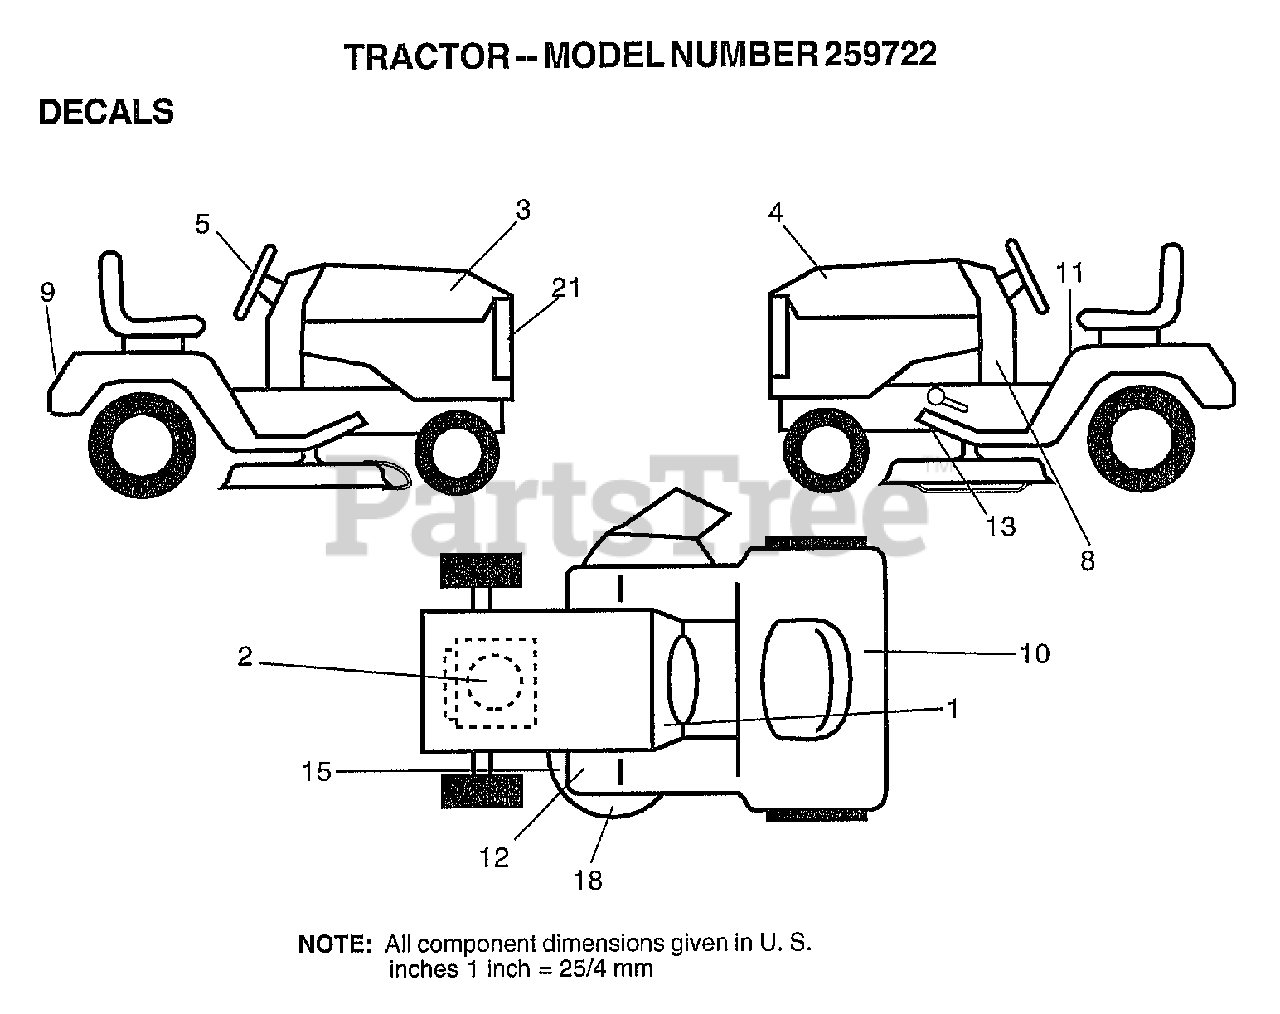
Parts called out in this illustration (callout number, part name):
1	"DECAL DASH,OPER."
2	DECAL HP ENGINE
3	DEECAL.HOOD.RH
4	DECAL.HOOD.LH
5	DECAL, INS STRG WH
8	DECAL.PNL.SD
9	DECAL.FENDER.LOGO
10	DECAL.BATRY.3-3908
11	"DECAL-FENDER,DANG"
15	DECAL
18	DECAL.MOWER.HOME
21	DECAL, GRILLE LENS
